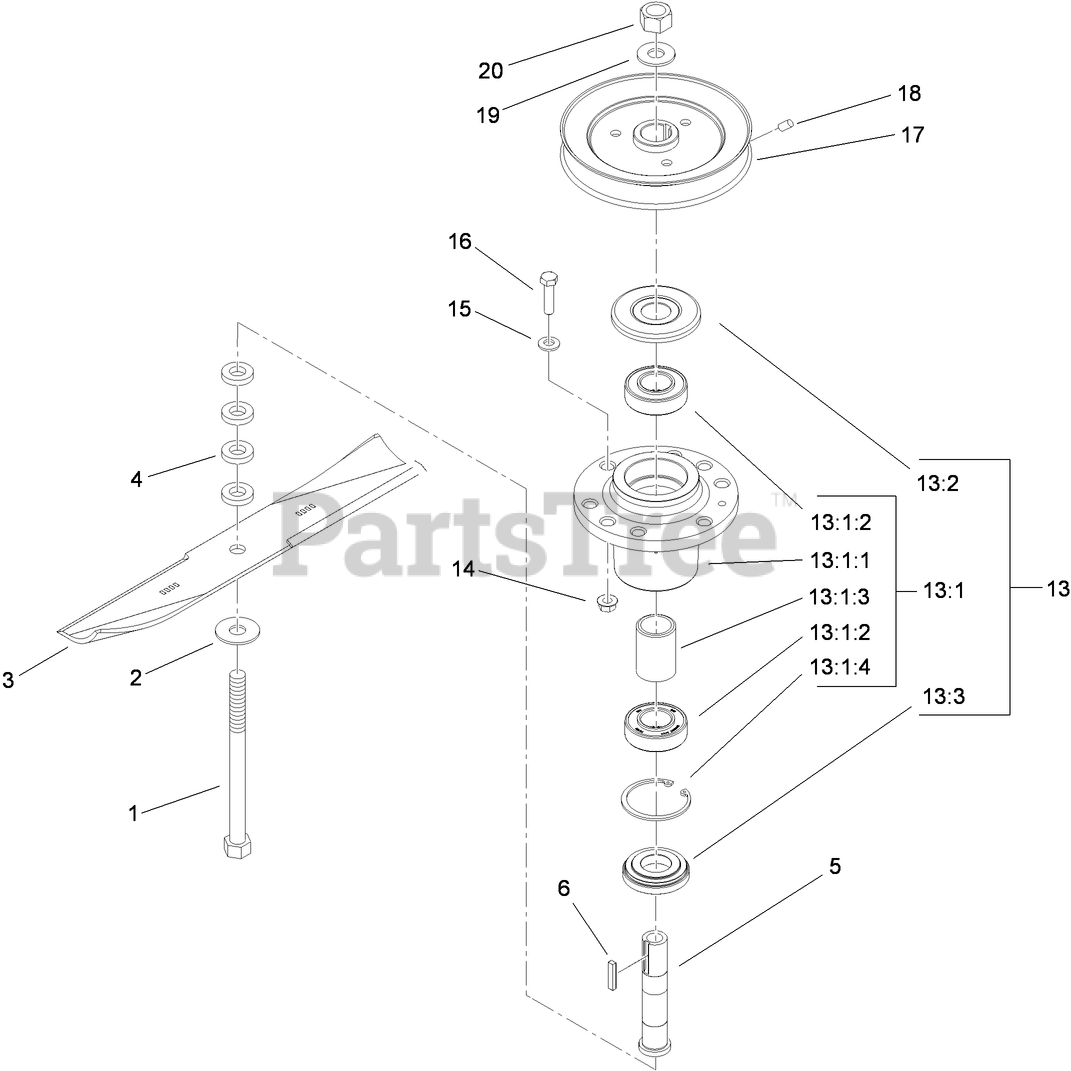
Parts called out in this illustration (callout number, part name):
1	SCREW-CAP, HH
2	WASHER-SPRING
3	BLADE-NOTCHED
3	BLADE-LIFT, LOW
4	SPACER
5	TUBE-SPINDLE, SHORT
13	CUTTER HOUSING ASM
13:1	CUTTER HOUSING ASM
13:1:1	HOUSING-SPINDLE
13:1:2	BEARING-JACKSHAFT
13:1:3	SPACER-BEARING
13:1:4	RING-SNAP
13:2	GUARD-BEARING, TOP
13:3	SPACER-GUARD, BOTTOM
14	NUT-HF
15	WASHER-SPRING
16	SCREW-HH
17	SHEAVE
18	SCREW-SET
19	WASHER-RETAINER, SHEAVE
20	NUT-HEX
